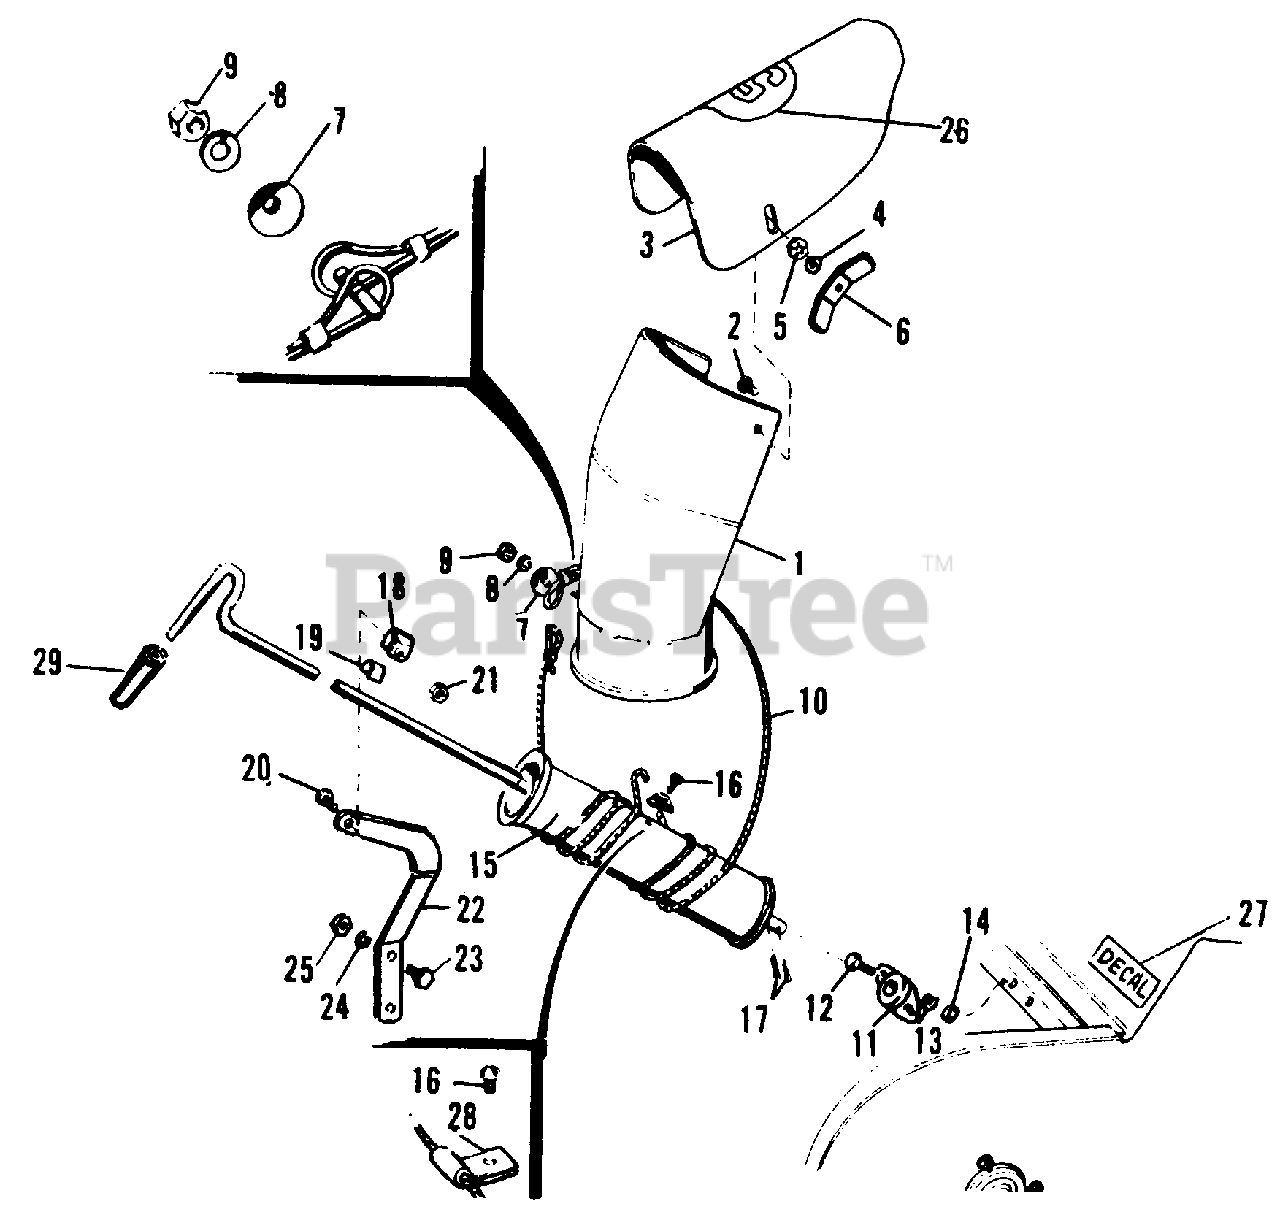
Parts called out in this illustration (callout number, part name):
1	Spout Assembly
2	Carriage Bolt, 5/16"-18 x 3/4"
3	Spout Extension
4	Washer, Plain 3/8"
5	Washer, Lock 3/8"
6	NUT, Wing, 5/16-18
8	Washer, Lock 5/16"
9	Nut, Hex Full 5/16"-18
10	Cable Assembly
12	Capscrew, Hex 1/4"-20 x 5/8"
13	Washer, Lock, 1/4"
14	Full Hex Nut, 1/4"-20
15	Rod Assy., Spout Control
16	Self-tapping Screw, 1/4"-20 x 3/8"
17	Cotter Pin, 3/32" x 5/8"
19	Liner, Guide
20	Capscrew, Hex, 5/16"-18 x 1-1/2"
21	Nut, Hex, Full, Lock, 5/16"-18
22	Rod Guide Support
23	Hex Capscrew, 3/8"-16 x 1" lg.
24	Lock Washer, 3/8"
25	Hex Nut, Full, 3/8"-16
28	Clamp (For Service Only)
29	Handle Grip
30	Pin, Cotter
